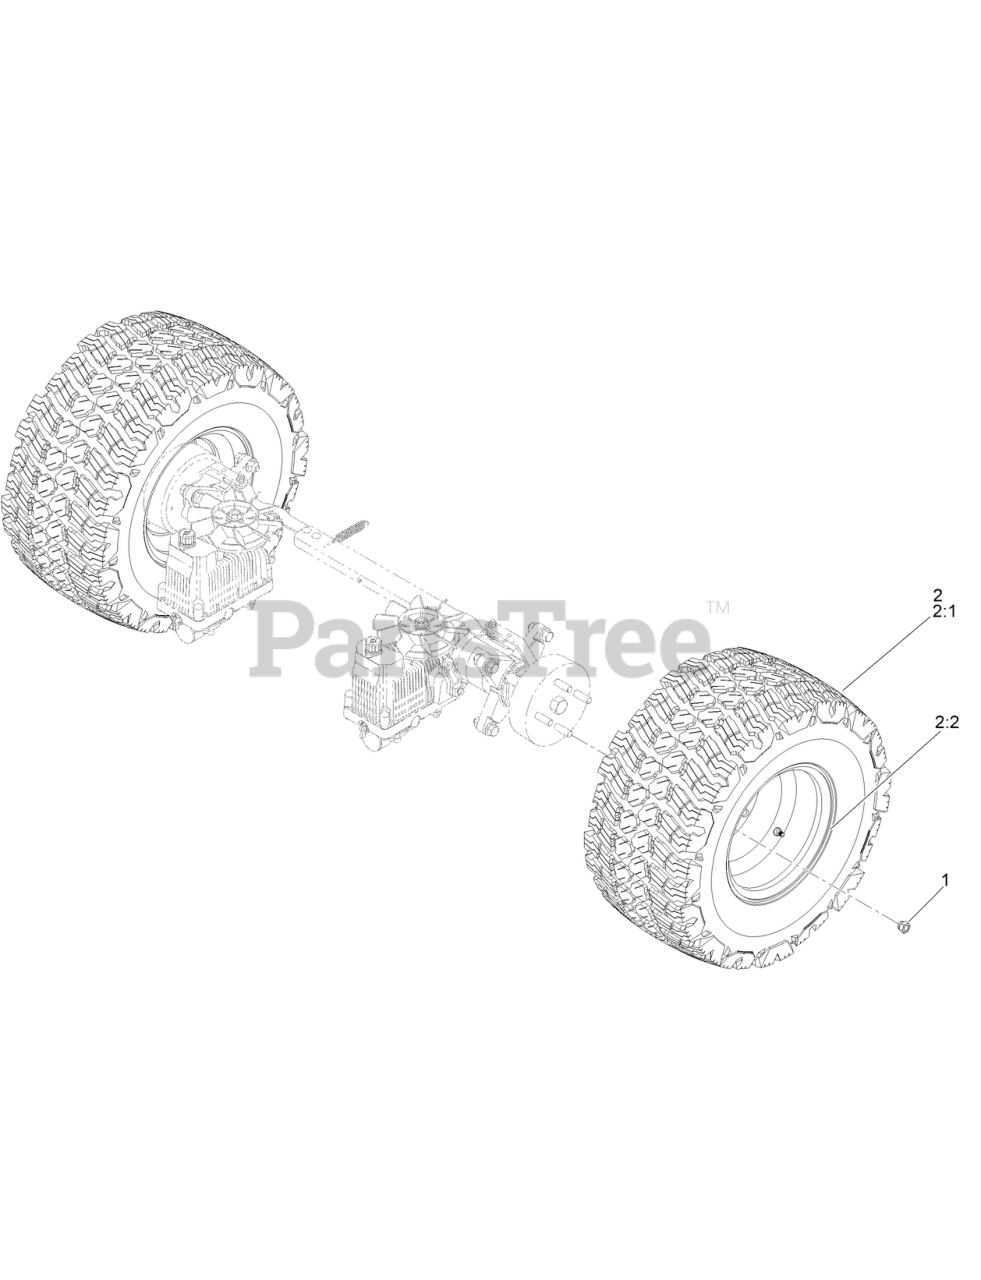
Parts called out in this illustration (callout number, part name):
1	1/2-20 LUGNUT
2	RZ RR 22X12-R10 SOFT RIDE AND WHEEL ASM
2:1	VS5010-2212R104 TIRE
2:2	10X8 STEEL WHEEL
